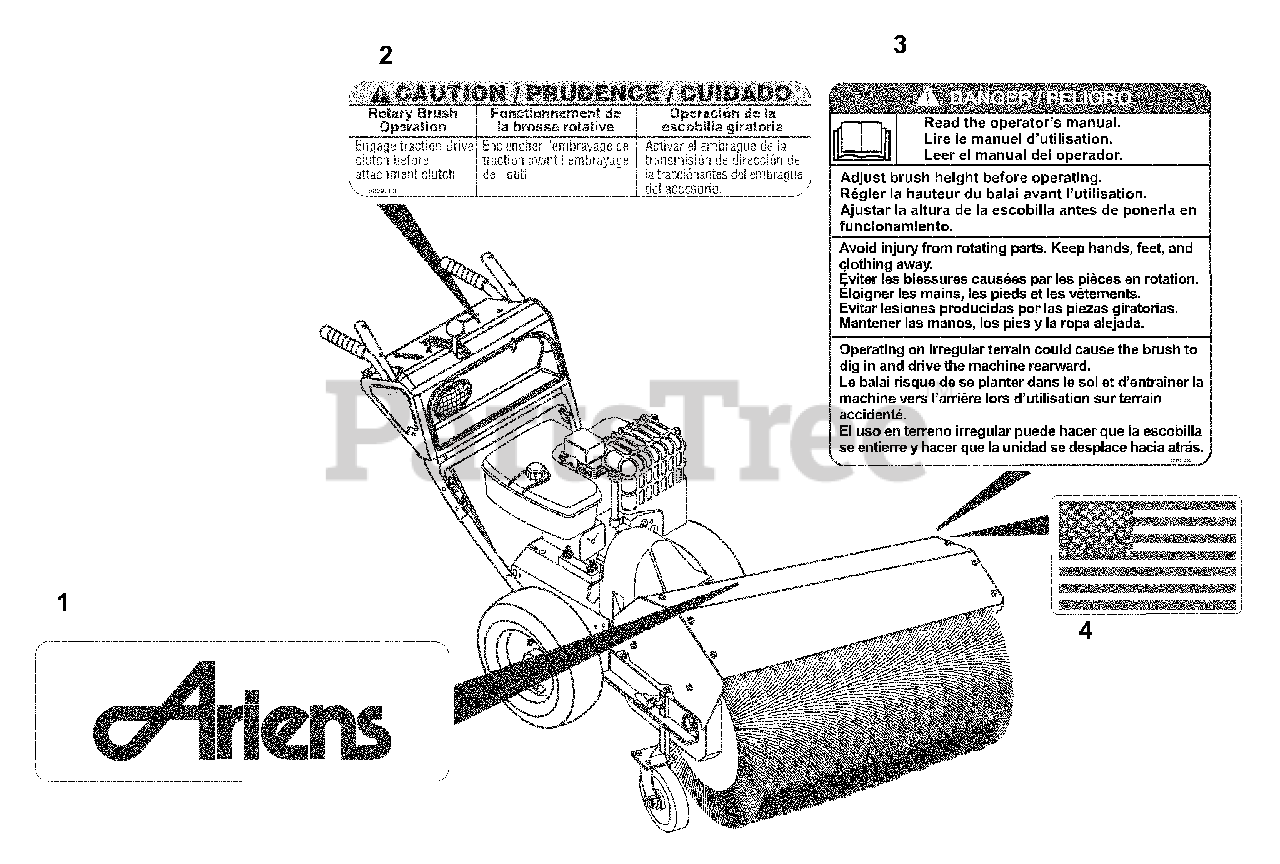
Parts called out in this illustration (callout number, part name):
1	DECAL - ARIENS
2	DECAL, CAUTION - BRUSH
3	DECAL, DANGER - POWER BRUSH
4	DECAL, AMERICAN FLAG
